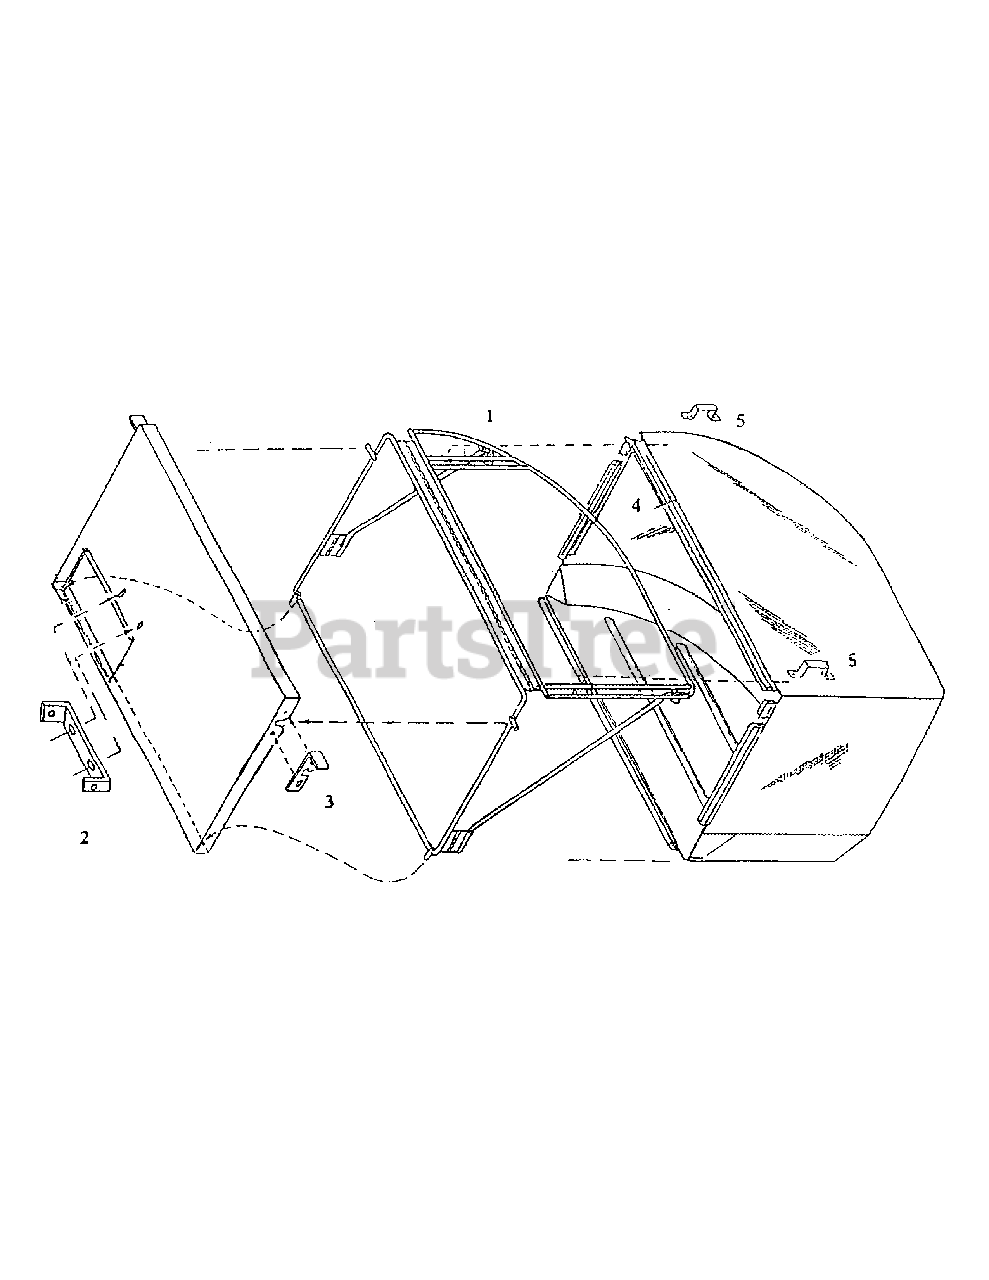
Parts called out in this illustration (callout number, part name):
1	Frame Assembly
2	Bolt on Bracket
3	Bag Release Latch
4	Cloth Bag
